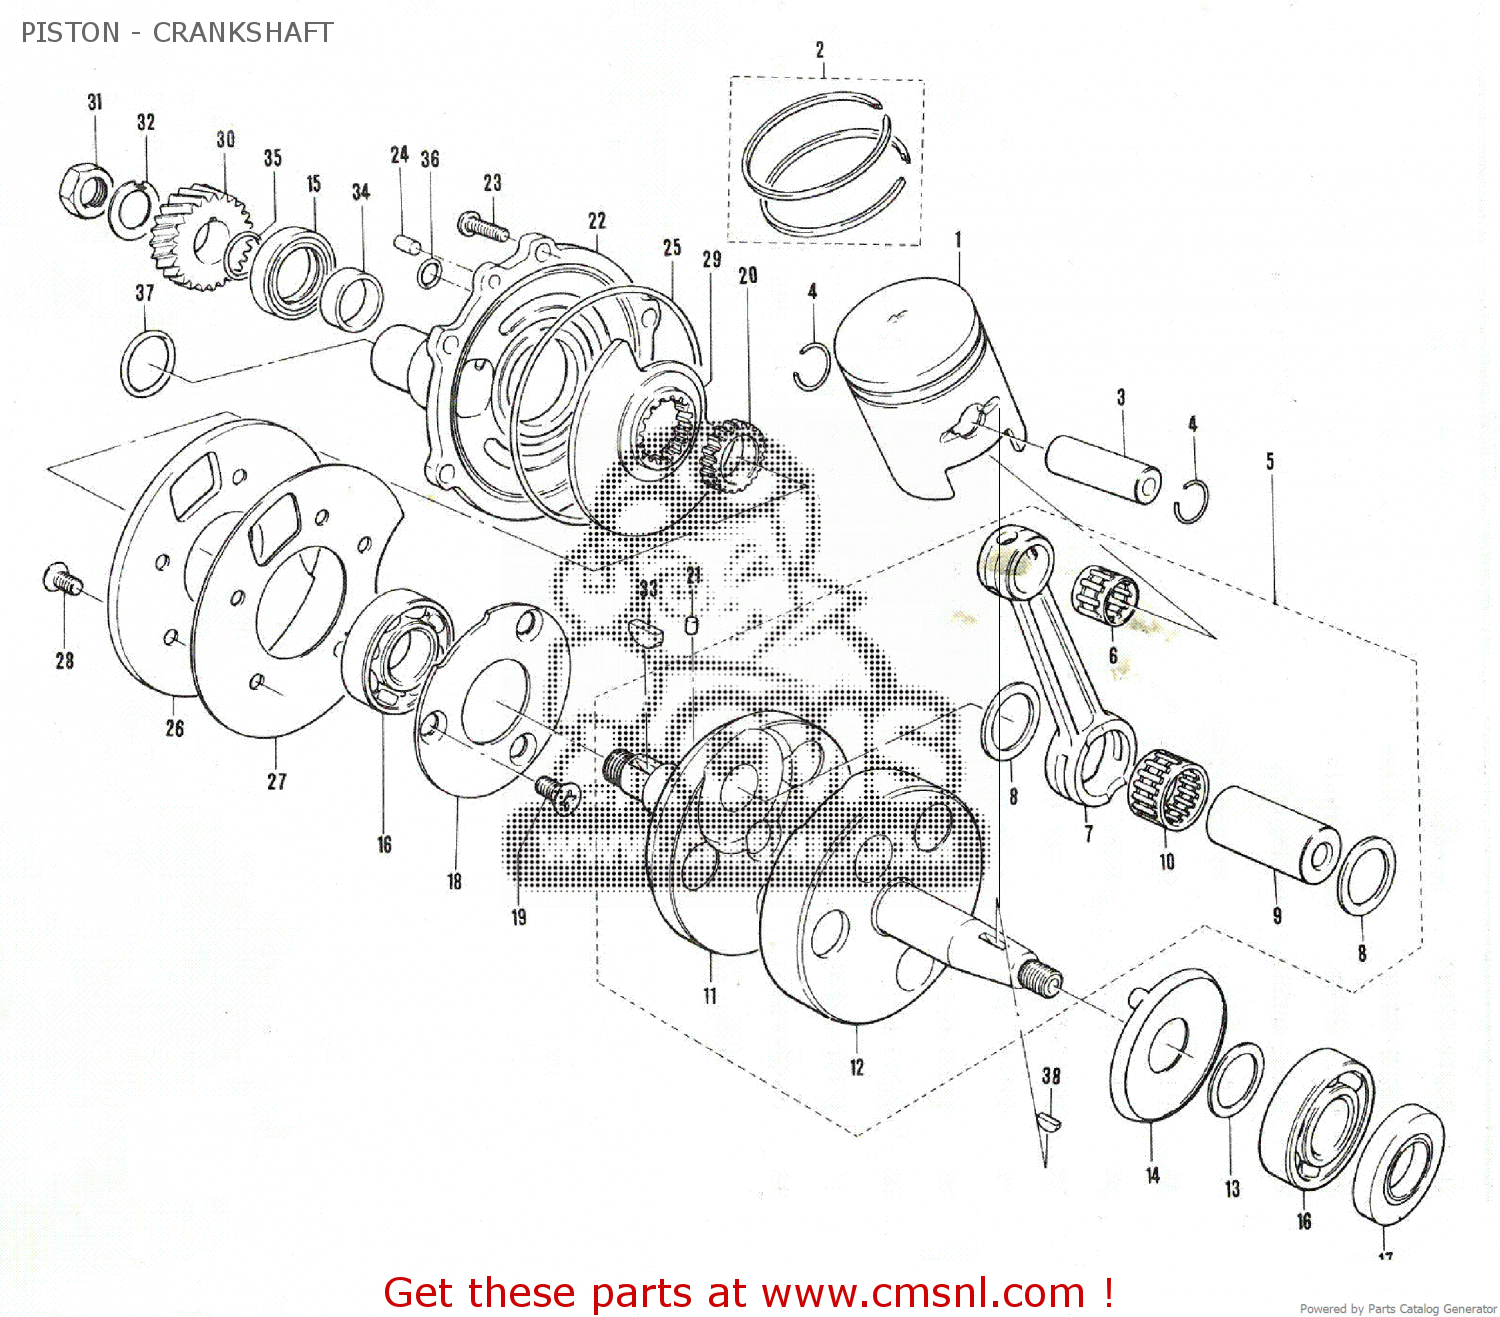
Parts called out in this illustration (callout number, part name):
1	PISTON
2	RING SET,PISTON
3	PIN,PISTON
4	RING,SNAP
5	CRANKSHAFT ASS'Y
6	BEARING
7	CONNECTING ROD
8	WASHER
9	CRANK PIN
10	BEARING 20X26X12
11	RH CRANKSHAFT
12	LH CRANKSHAFT
13	THRUST WASHER
14	PLATE,CRANKSHAFT OIL GUIDE
15	SEAL,OIL(25X40X7)
16	BEARING
17	SEAL,OIL(20X40X7)
18	PLATE
19	SCREW
20	GUIDE,DISC VALVE
21	PIN
22	SEAT,CRANKCASE OUTER VALVE
23	SCREW
24	PIN
25	O RING(D:2,ID:99)
26	SEAT,INNER DISC VALVE
27	GASKET,INNER DISC VALVE (NAS)
28	SCREW
29	PLATE,DISC VALVE
30	GEAR,PRIMARY DRIVE
31	NUT
32	WASHER
33	KEY 4MM
34	SPACER
35	O-RING
36	O RING(D:2.5,ID:7.5)
37	O RING(D:3.5,ID:25.7)
38	KEY
